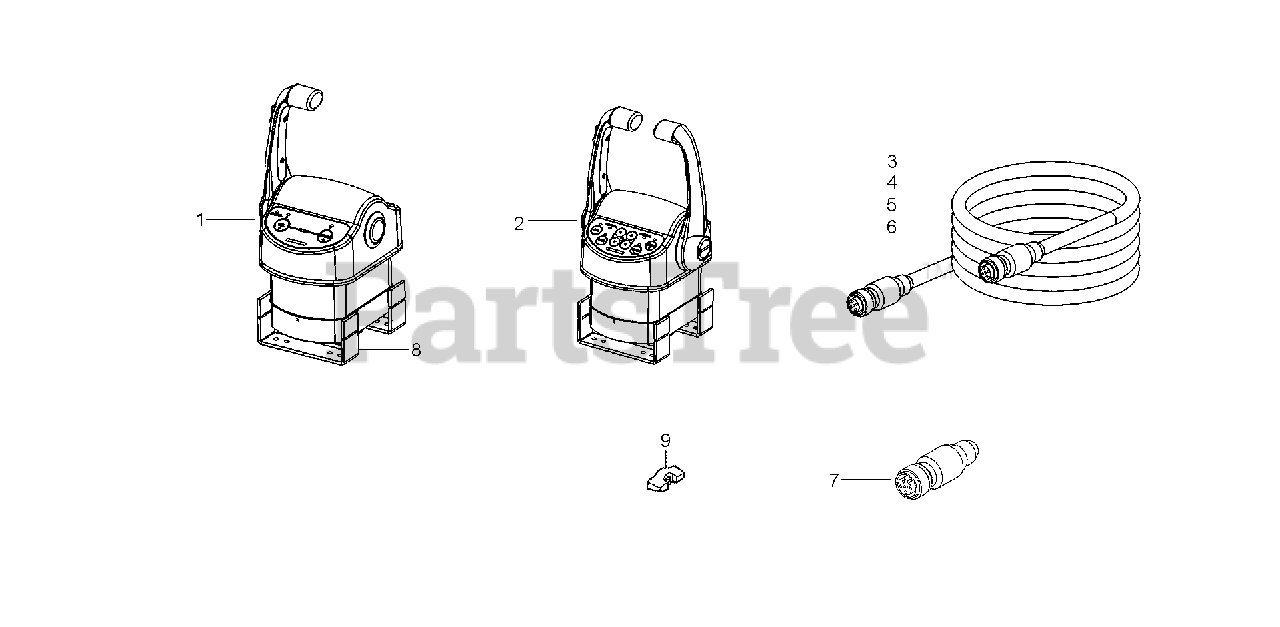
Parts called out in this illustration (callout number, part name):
1	CONTROL, IST SINGLE ENGINE
2	CONTROL, IST MULTI ENGINE
3	STATION CABLE (15')
4	STATION CABLE (20')
5	STATION CABLE (25')
6	STATION CABLE (30')
7	F TERMINATOR, IST
8	CLAMP, INSTALLATION
